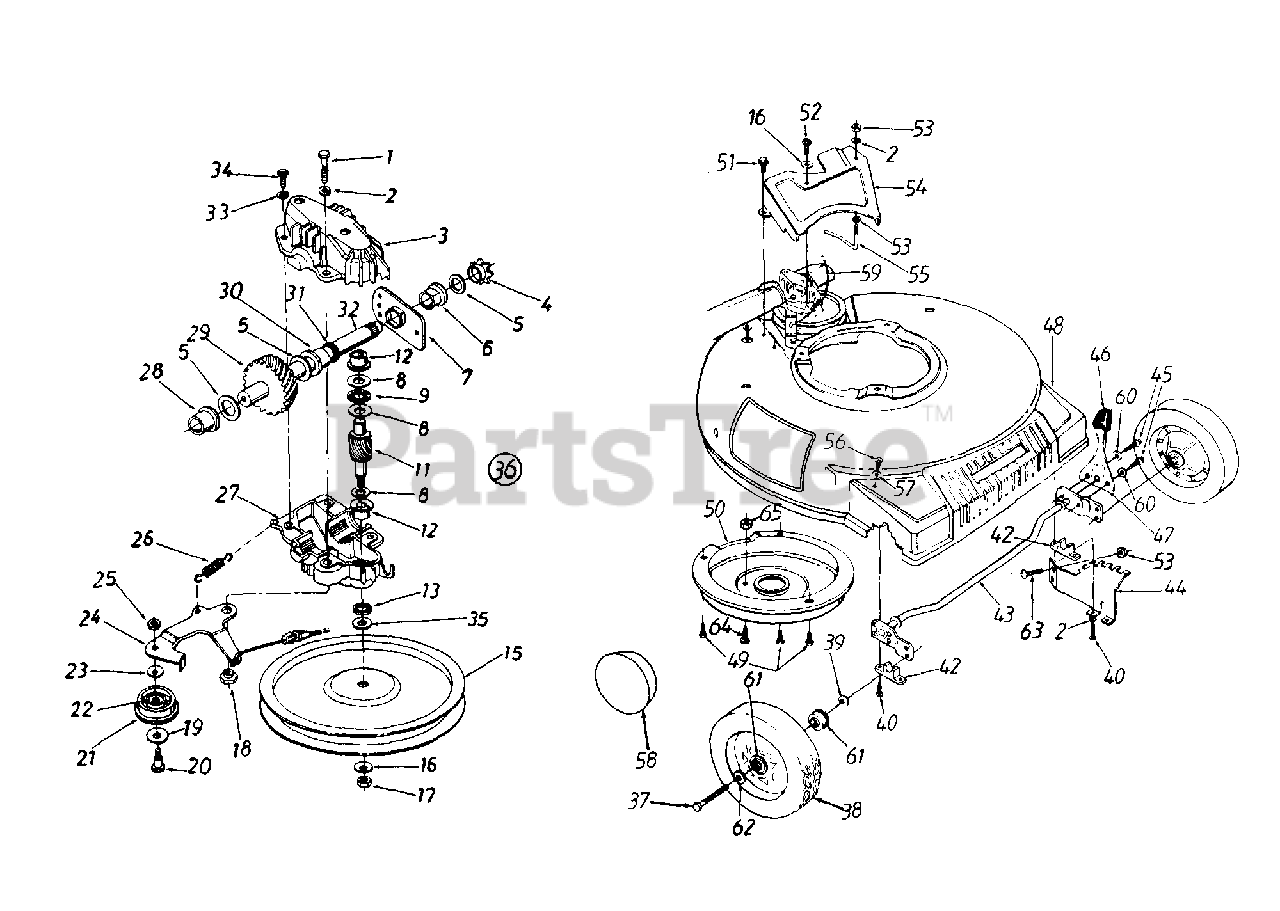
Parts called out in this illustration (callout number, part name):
1	Hex Patch Bolt 1/4-20 x 1.25"
2	L-Wash. 114" I.D.
3	Upper Hsg. Half
4	#48 Sprocket 7 T x 1/2 Pitch
5	Fl-Wash. 5/8" I.D. x .030
6	Hex Flange Brg..631" I.D.
8	Thrust Wash..382" I.D. x .70" O.D.
9	Thrust Bearing .375" I.D. x .812" O.D.
11	11 Tooth Pinion Shaft
12	Flange Bearing
13	Oil Seal
15	Fl-Pulley 5.06" O.D.
16	Bell-Wash. .265" I.D. x .75"
17	Hex L-Nut 1/4-28 L.H. Thd.
18	Shld. Spacer .375" Dia. x .170
19	Fl-Wash. .390" I.D. x 1.0"
20	Shld. Bolt .375" Dia. x .40"
21	Fl-Idler Plastic 1.50" Dia.
22	Needle Brg. .375" x .31
24	Idler Brk't. Ass'y.
25	Hex Patch L-Nut 1/4-28 Thd.
26	Extension Spring 1.12" Lg.
27	Lower Hsg. Half
28	Flange Bearing .566 Dia.
29	33 Tooth Helical Gear
30	Flange Bearing .629 Dia.
31	Oil Seal .625 Dia. f
32	Gear Sprocket Shaft
33	L-Wash. #10 I.D.
34	Hex B-Tap Scr. #10 x .62"
35	Hex Washer .26" x .88"
36	Transmission Comp.
37	Front Axle Bolt
38	Wheel Ass'y. Comp.
39	Bell-Wash..380" I.D. x .88
40	Hex Wash. Hd. Tap Scr. 1/4-20 x 1" Lg.
42	Block Bushing
45	Mex TT-Tap Scr. 1/4-20 x .38"
46	Knob
47	Spring Lever
48	Plastic Front End
49	Hex B-Tap Scr. 1/4" x .38"
52	Hex Wash. Hd. B-Tap Scr. 1/4 x .62" (Spec.)
53	Hex Flange L-Nut 1/4-20 Thd.
56	Torx Scr. 5/16 x .75" Lg.
57	Bell-Wash..345" I.D. x .88"
58	Hub Cap
59	S.P. Cable 44" Lg.
60	External L-Wash. 1/4" I.D.
61	Ball Bearing 1/2" I.D.
62	Wave Wash..53" I.D.
63	Carriage Bolt .5" Lg.
64	Mach. Scr. 1/4-20 x 2" Lg.
65	Mex L-Nut 1/4-20 Thd.
